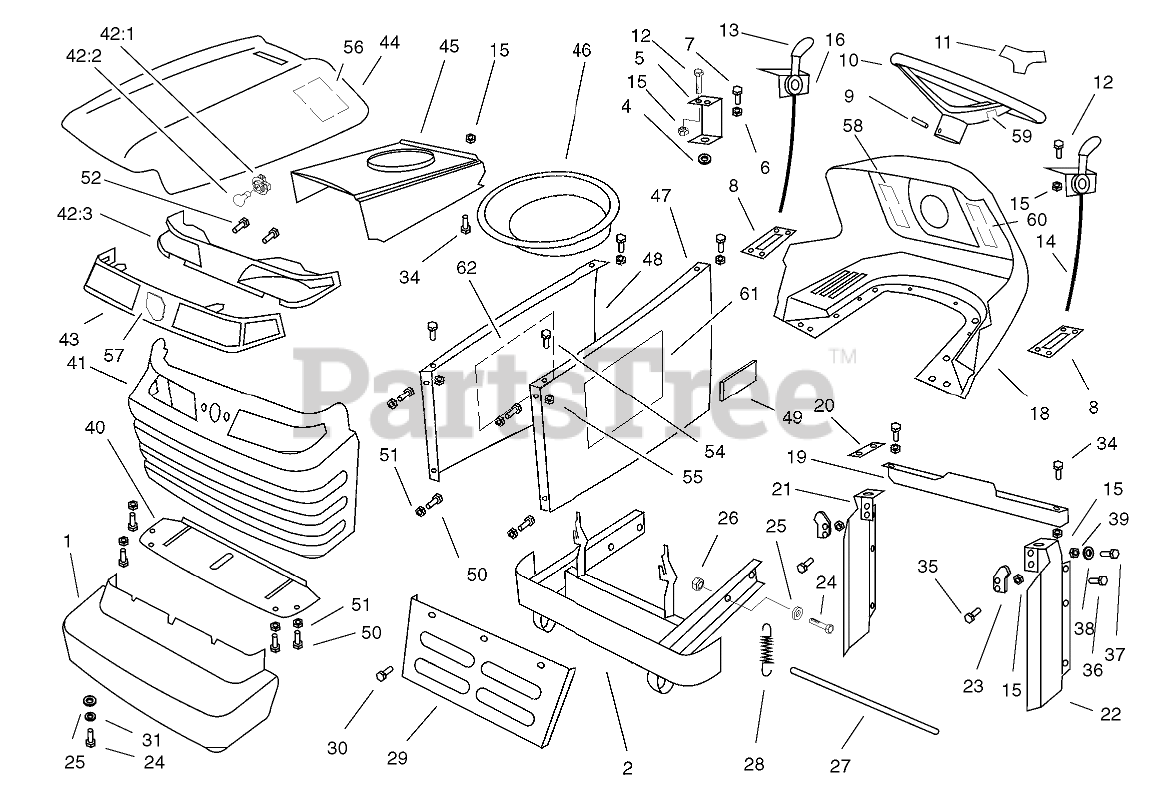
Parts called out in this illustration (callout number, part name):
1	COVER-BUMPER
2	BUMPER
4	BUSHING
5	HOLDER-TANK, FUEL
6	NUT-LOCK
9	PIN-SPIROL
10	STEERING WHEEL-14"
11	COVER-WHEEL, STEERING
12	SCREW-FLAT HEAD
14	CONTROL-CHOKE (TWIN)
15	NUT-LOCK
16	CONTROL-THROTTLE (TWIN)
18	PANEL-DASH
20	BRACKET
21	PANEL-RIGHT
22	PANEL-LEFT
23	LATCH-HOOD
24	SCREW-HH
25	WASHER-PLAIN
26	NUT-LOCK, NI
27	BAR-SAFETY
28	SPRING-HOOD
29	SHIELD-HEAT
30	SCREW-TAP
31	WASHER-SPRING
32	SCREW-HEX
33	WASHER-FLAT
38	WASHER
39	NUT-HEX
40	BRACKET
42:1	SOCKET-LIGHT
42:2	BULB
42:3	REFLECTOR-LIGHT
43	LENS - HEADLIGHT
44	HOOD-TOP
45	HOOD - BAFFLE
46	PLENNUM-AIR
47	SIDE-HOOD, RH
48	SIDE-HOOD, LH
49	FOAM-SIDEPANEL
51	NUT-HEX
52	SCREW-PLASTITE
54	SCREW-HWH
56	FOAM-HOOD
57	EMBLEM-HORSEHEAD
58	DECAL
59	DECAL
60	DECAL-CHOKE/PTO
61	DECAL-HOOD, LH
62	DECAL-HOOD, RH
